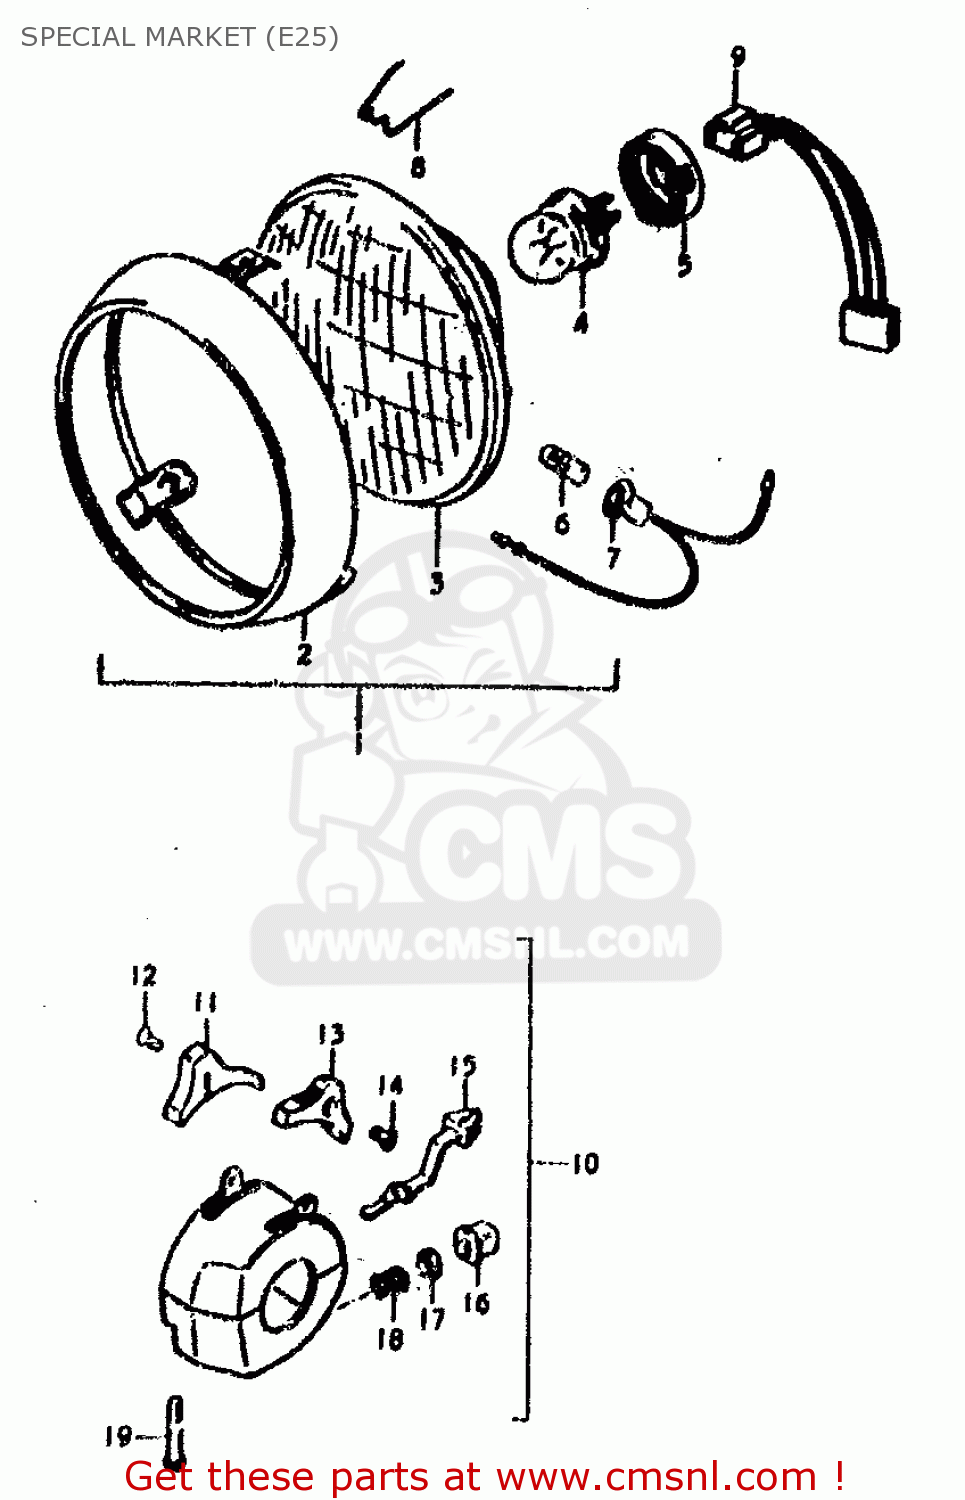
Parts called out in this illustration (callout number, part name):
1	HEADLAMP ASSY
2	RIM
3	UNIT
4	BULB(12V45/40W)
5	SETTER,BULB
6	BULB(12V4W)
7	SOCKET
8	SPRING,HEAD LA
9	LEAD WIRE,HEADLAMP
10	SWITCH ASSY,HANDLE LH
11	KNOB,LIGHTING SWITCH
12	SCREW
13	KNOB,DIMMER SWITCH
14	SCREW
15	KNOB,TURNSIGNAL
16	BUTTON,HORN
17	CONTACT
18	SPRING
19	SCREW
